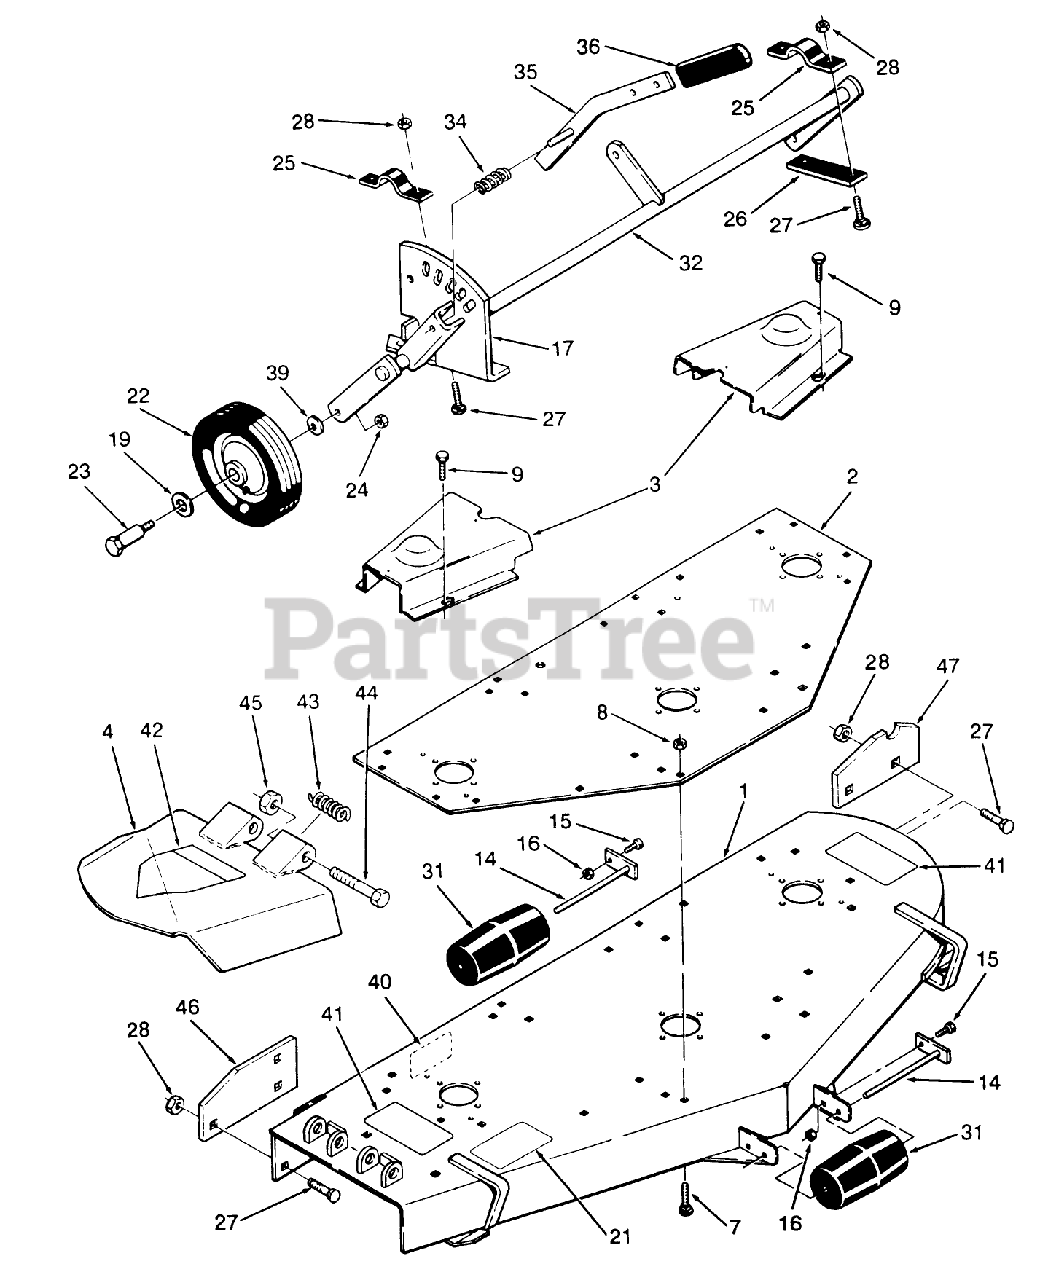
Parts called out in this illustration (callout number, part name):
1	WLDMT-60" MWR DEC R
2	PLATE-TOP REINFOR R
3	Belt Cover
4	Chute Guard Assembly
7	Bolt
8	NUT
9	Bolt
14	ROLLER-SHAFT
15	Bolt
16	Nut
17	Quadrant
19	Washer
21	DECAL-BELT INSTALL
22	ASSY-GAUGE WHEEL
23	Bolt 3/8-16 x 3 1/4
24	NUT
25	Clamp
27	BOLT-CARR
28	NUT
31	ROLLER-ANTI SCALP
32	Gage Wheel Support
34	SPRING-COMPRESSION
35	Lever
39	SPACER
40	DECAL-HOC
41	DECAL-DANGER, THROWN OBJECT
42	DECAL-DANGER
43	SPRING
44	SCREW-HH
45	NUT-LOCK, NI
46	Wear Plate RH
47	PLTE WEAR LH
